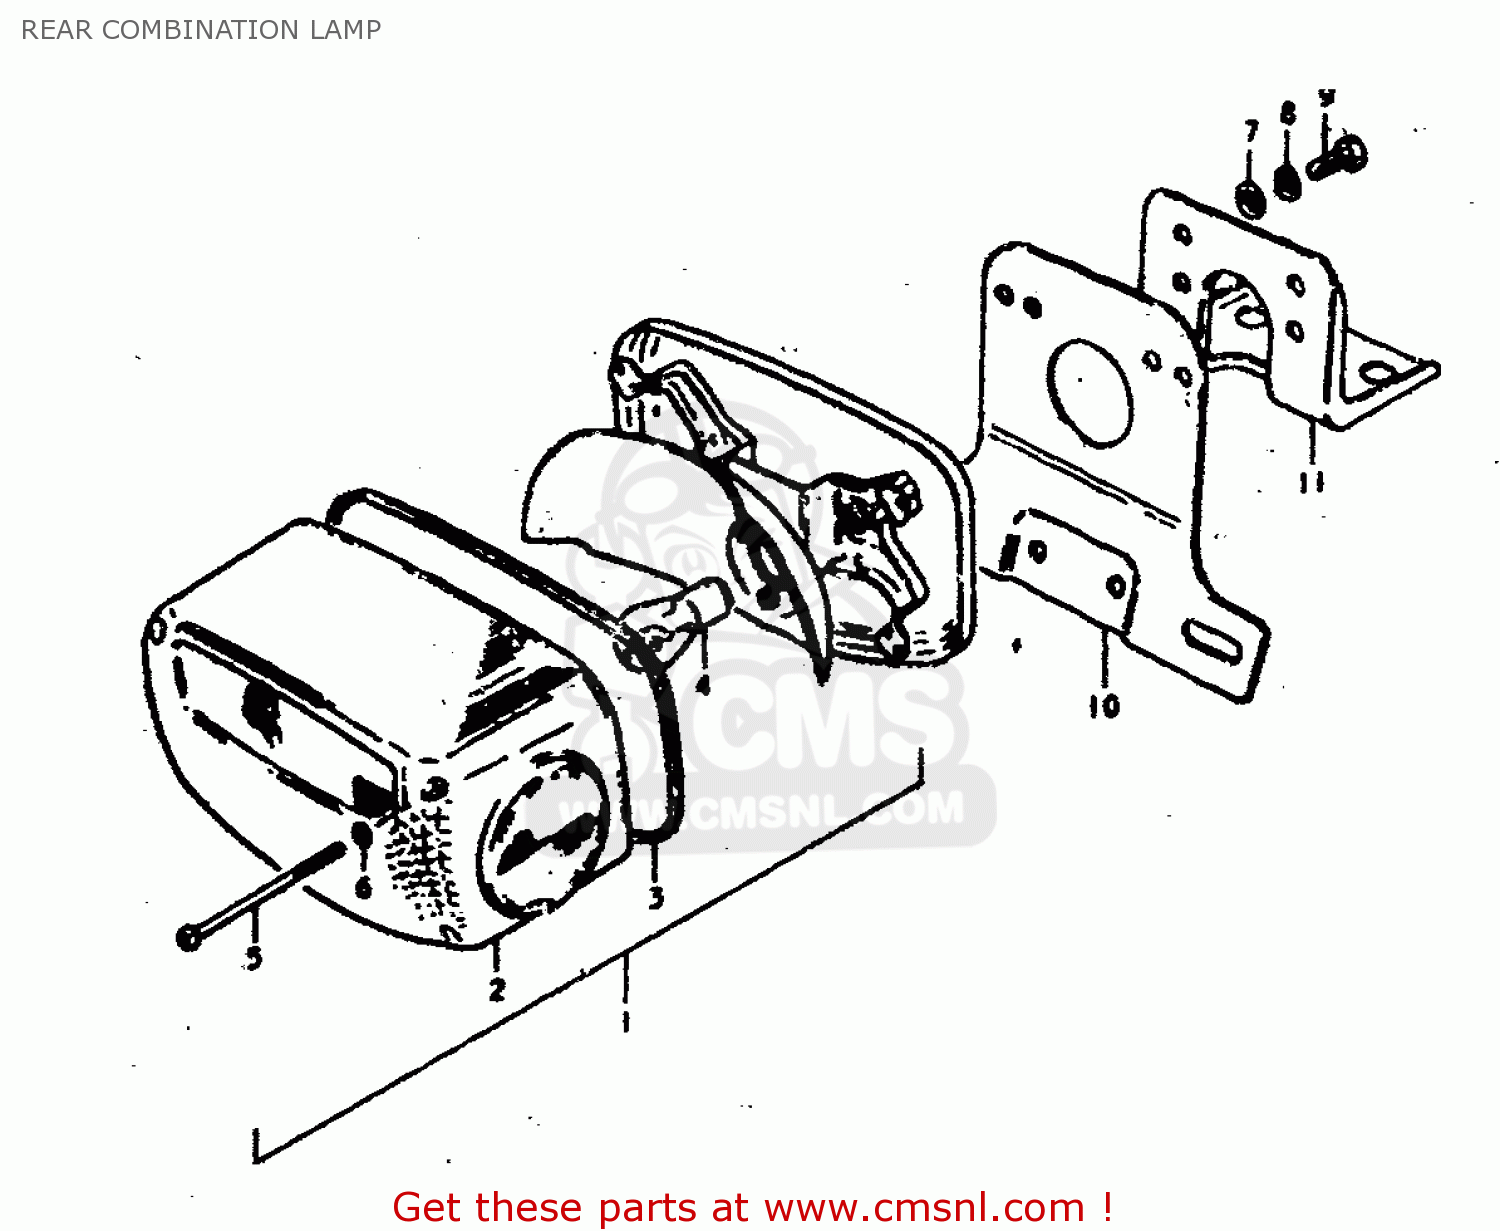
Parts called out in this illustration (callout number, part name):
1	LAMP ASSEMBLY,REAR COMBINATION
2	LENS,REAR COMBINATION LAMP
3	GASKET (NAS)
4	BULB(12V23W)
5	SCREW
6	GASKET (NAS)
7	WASHER
8	LOCK WASHER
9	BOLT
10	BRACKET,LICENSE PLATE
11	BRACKET,LICENSE PLATE
